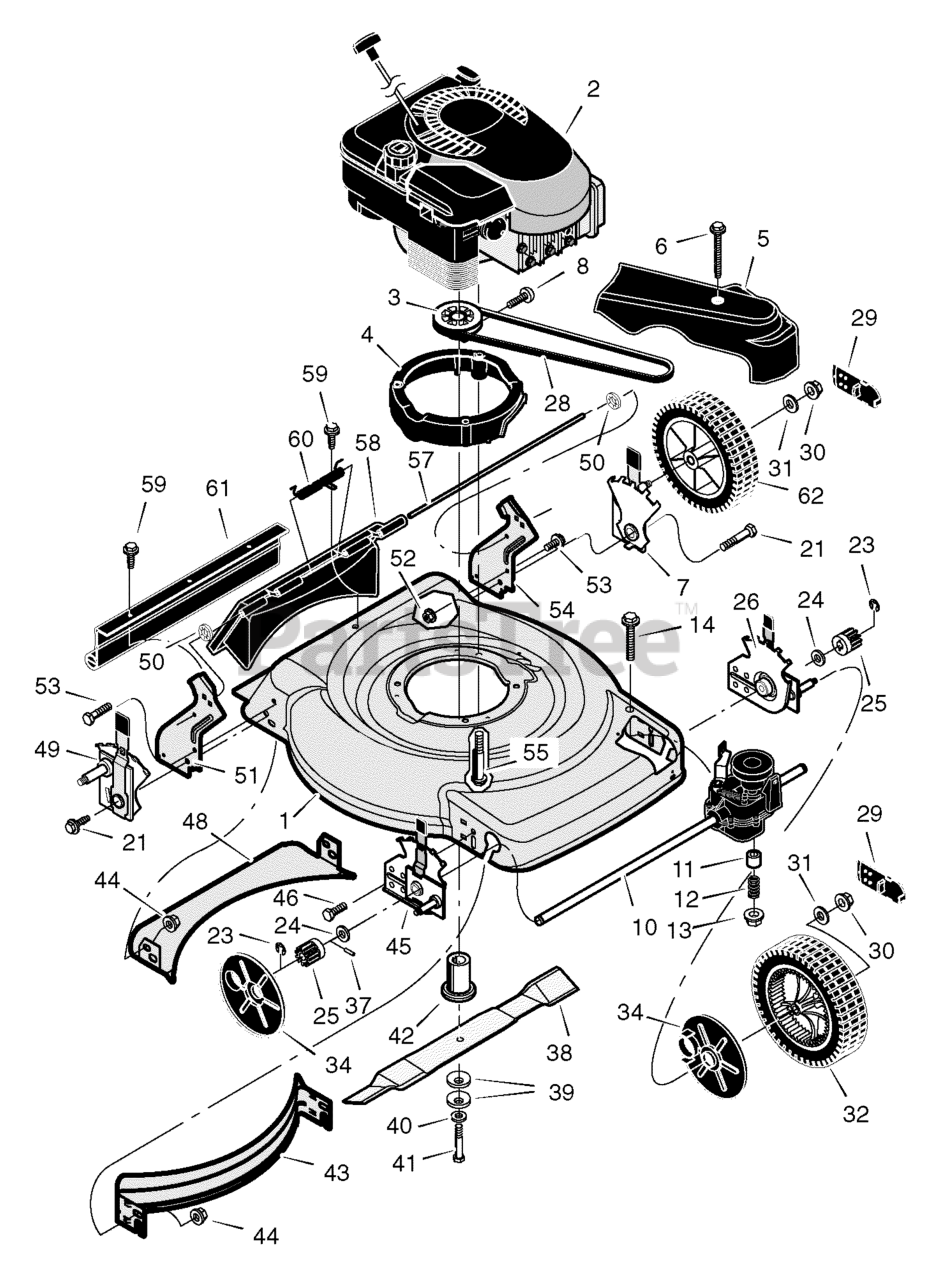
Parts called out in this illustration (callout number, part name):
1	Housing
2	Engine *
3	Pulley, Drive
4	Spacer, Engine
5	Cover, Belt (Black)
5	Cover, Belt (Gray)
7	Adjuster, Left Rear Height
10	Transmission *
11	Spacer
12	Spring, Compression
13	Nut
14	Bolt
23	E-Ring
24	Washer
25	Gear, Pinion
26	Adjuster, Left Front Height
29	Cap, Hub
30	Nut, Flange
31	Washer
32	Wheel & Tire, Front
34	Cover, Dust
37	Pin, Drive
39	Washer, Belleville
40	Washer
42	Adapter, Blade
43	Baffle, Front
44	Nut, Flange
45	Adjuster, Right Front Height
46	Bolt
48	Baffle, Rear
49	Adjuster, Right Rear Height
50	Retainer, Push
51	Bracket, Right Handle
52	Nut, Flange
53	Bolt
54	Bracket, Left Handle
55	Bolt, Engine
57	Rod, Pivot
58	Door, Rear (Black)
58	Door, Rear (Gray)
60	Spring
61	Guard, Rear
62	Wheel & Tire, Rear
